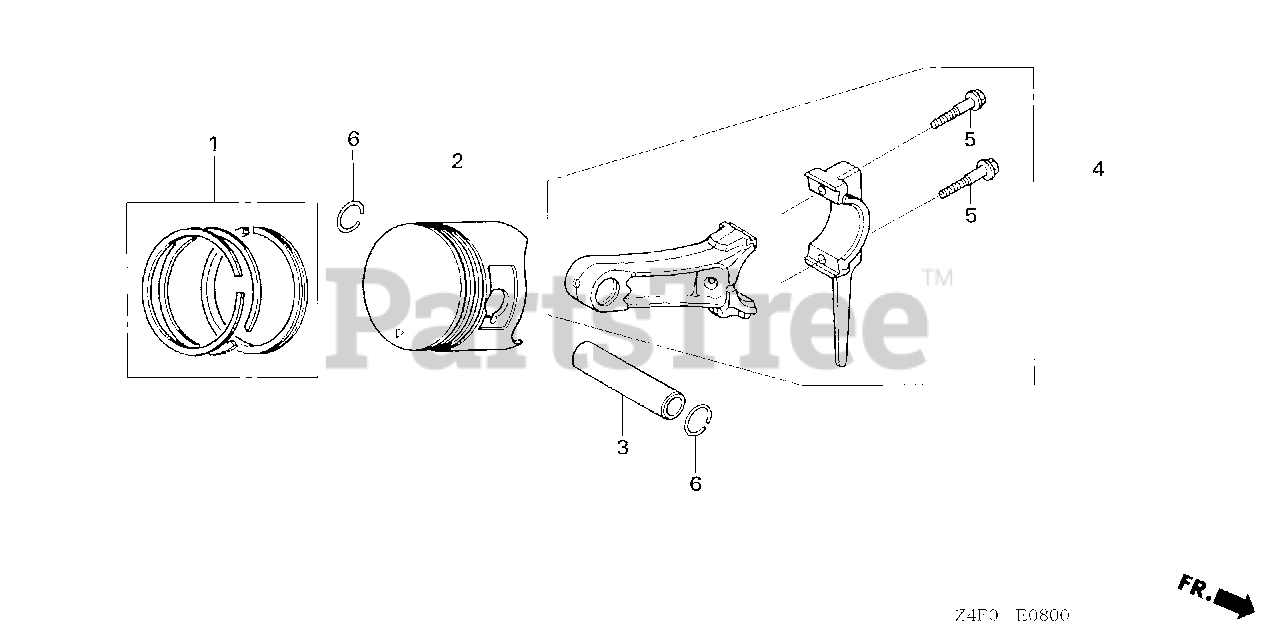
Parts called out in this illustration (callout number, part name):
1	RING SET, PISTON (STD) (TEIKOKU)
1	RING SET, PISTON (STD) (NIPPON)
1	RING SET, PISTON (0.25) (TEIKOKU)
1	RING SET, PISTON (0.25) (NIPPON)
1	RING SET, PISTON (0.50) (TEIKOKU)
1	RING SET, PISTON (0.50) (NIPPON)
1	RING SET, PISTON (0.75) (TEIKOKU)
1	RING SET, PISTON (0.75) (NIPPON)
2	PISTON (STD)
2	PISTON (0.25)
2	PISTON (0.50)
2	PISTON (0.75)
3	PIN, PISTON
4	ROD ASSY., CONNECTING
5	BOLT, CONNECTING ROD
6	CLIP, PISTON PIN (13MM)
